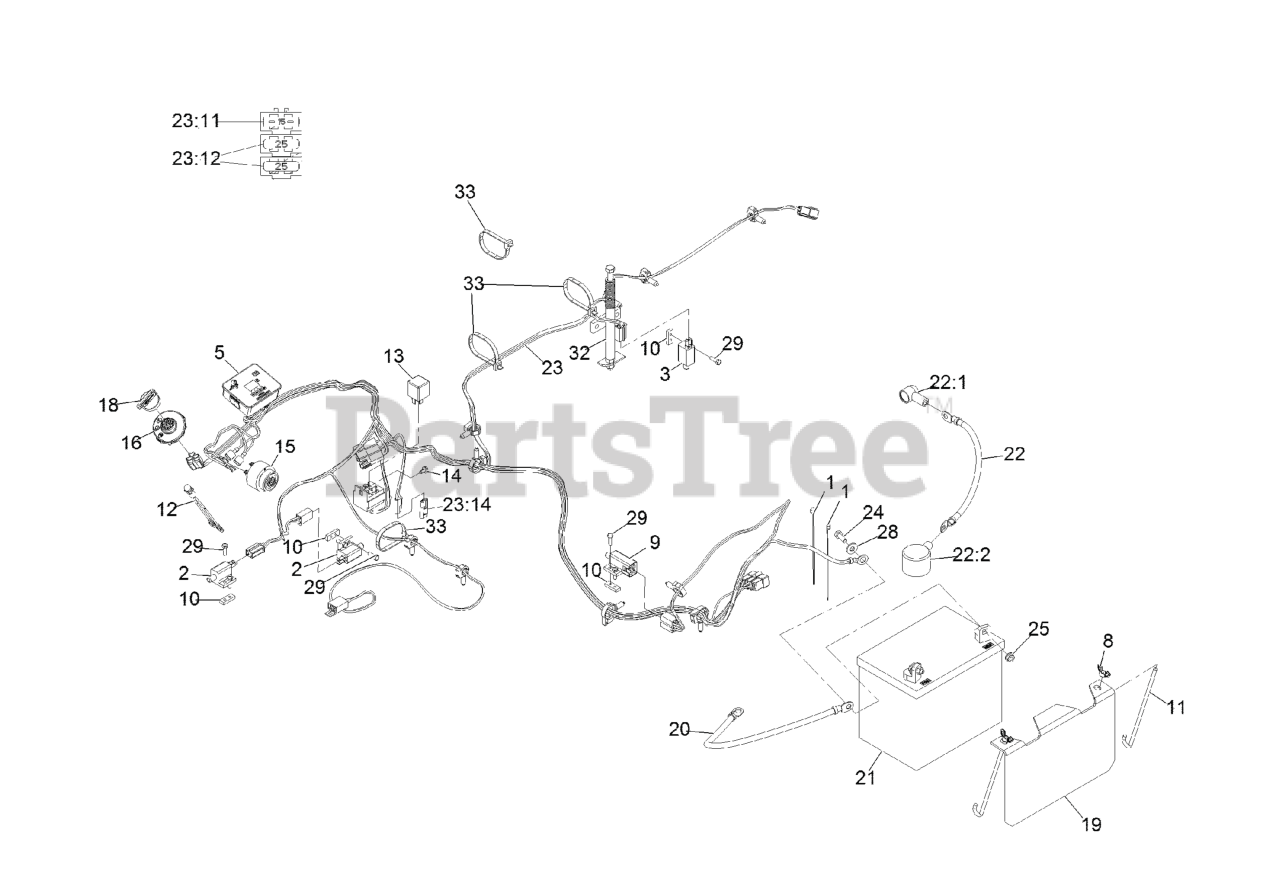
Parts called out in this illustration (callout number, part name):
1	TIE-CABLE
2	SWITCH-OPEN, NORMALLY
3	SWITCH-CLOSED, NORMALLY
5	HOUR METER ASM
8	WINGNUT
10	PLATE-TAPPED
11	BOLT-HOLDDOWN
12	INDICATOR-LED, RED
14	SCREW-HWH
15	ALARM-TONE, DUAL
16	SWITCH-IGNITION
18	KEY-IGNITION
19	HOLD DOWN-BATTERY
20	CABLE-BATTERY, NEGATIVE
21	Battery
22	CABLE-BATTERY, POSITIVE
22:1	INSULATOR-SOLENOID
22:2	INSULATOR-BATTERY
23	HARNESS-WIRING
23:11	FUSE-BLADE, 15 AMP
23:12	FUSE-BLADE, 25 AMP
23:14	CAP-PLUG
24	SCREW-HH
28	WASHER-FLAT
32	HOPPER SWITCH ACTUATOR AS
33	TIE-PLASTIC
